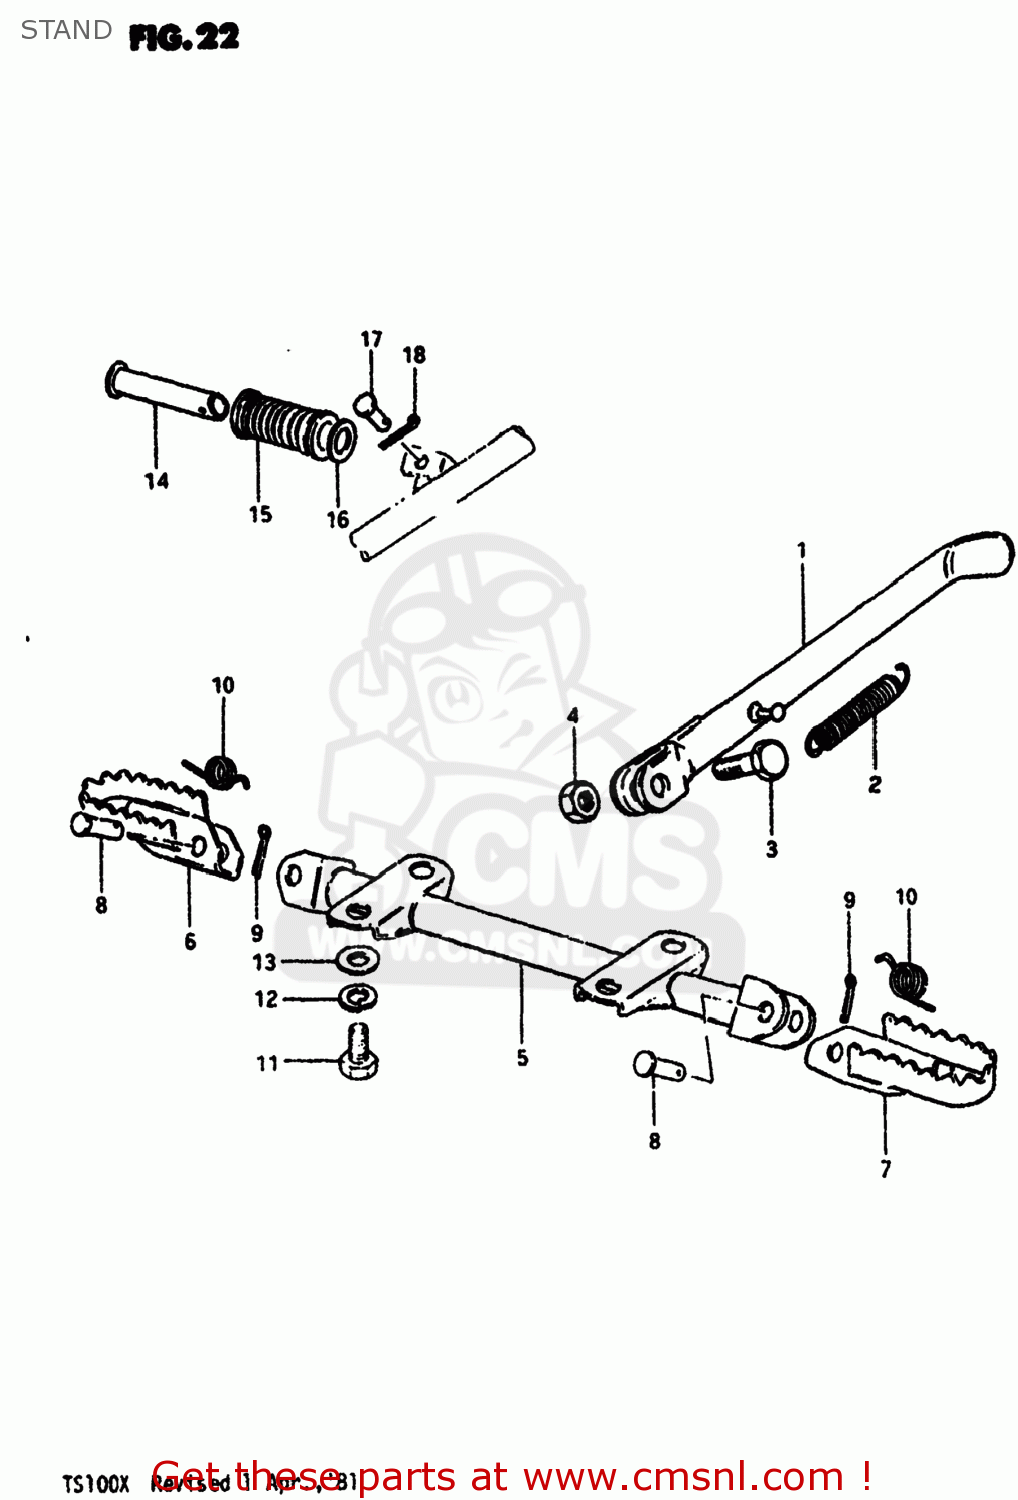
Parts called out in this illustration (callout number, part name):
1	STAND,SIDE
2	SPRING
3	BOLT(10X30)
4	NUT
5	BAR,FR FOOTREST
6	FOOTREST,FRONT
7	FOOTREST
8	PIN
9	PIN 20X20
10	SPRING
11	BOLT
12	LOCK WASHER
13	WASHER
14	BAR,FOOTREST RUBBER
15	RUBBER,PILLION FOOTREST
16	WASHER (19.5X32X2)
17	PIN
18	PIN 20X20
